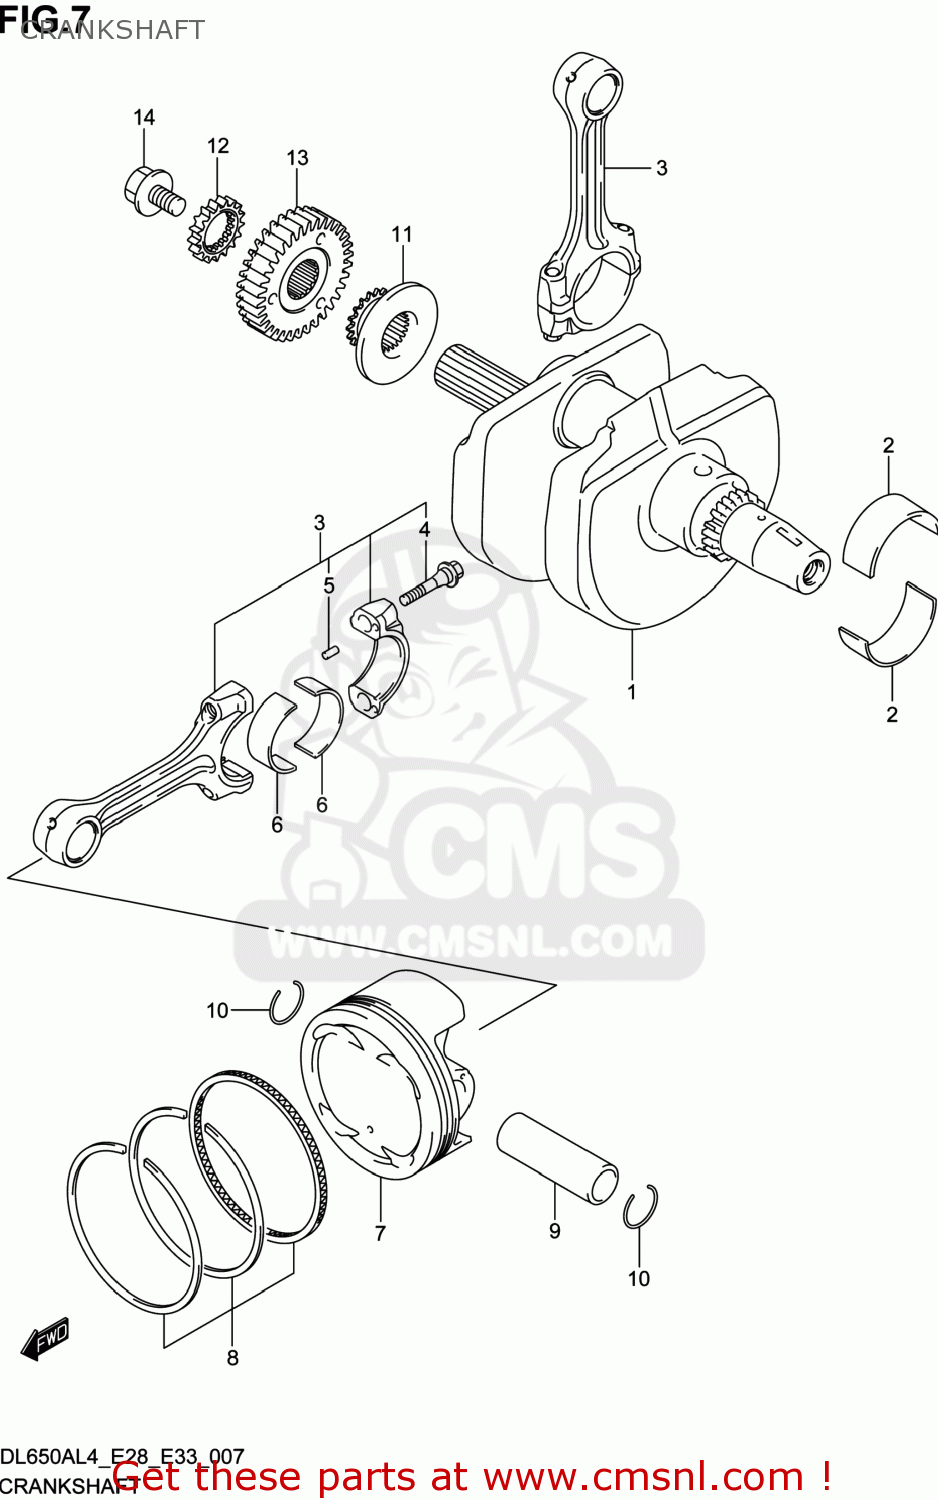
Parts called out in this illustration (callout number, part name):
1	CRANKSHAFT
2	BEARING,CRANKSHAFT
3	CONNECTING ROD ASSY
4	BOLT,CONNECTING ROD
5	PIN
6	BEARING,CRANK PIN
7	PISTON
8	RING SET,PISTON
9	PIN,PISTON
10	CIRCLIP,PISTON PIN
11	SPROCKET,CAM CHAIN DRIVE
12	GEAR,WATER PUMP DRIVE
13	GEAR ASSY,PRIMARY DRIVE
14	BOLT(10X19)
